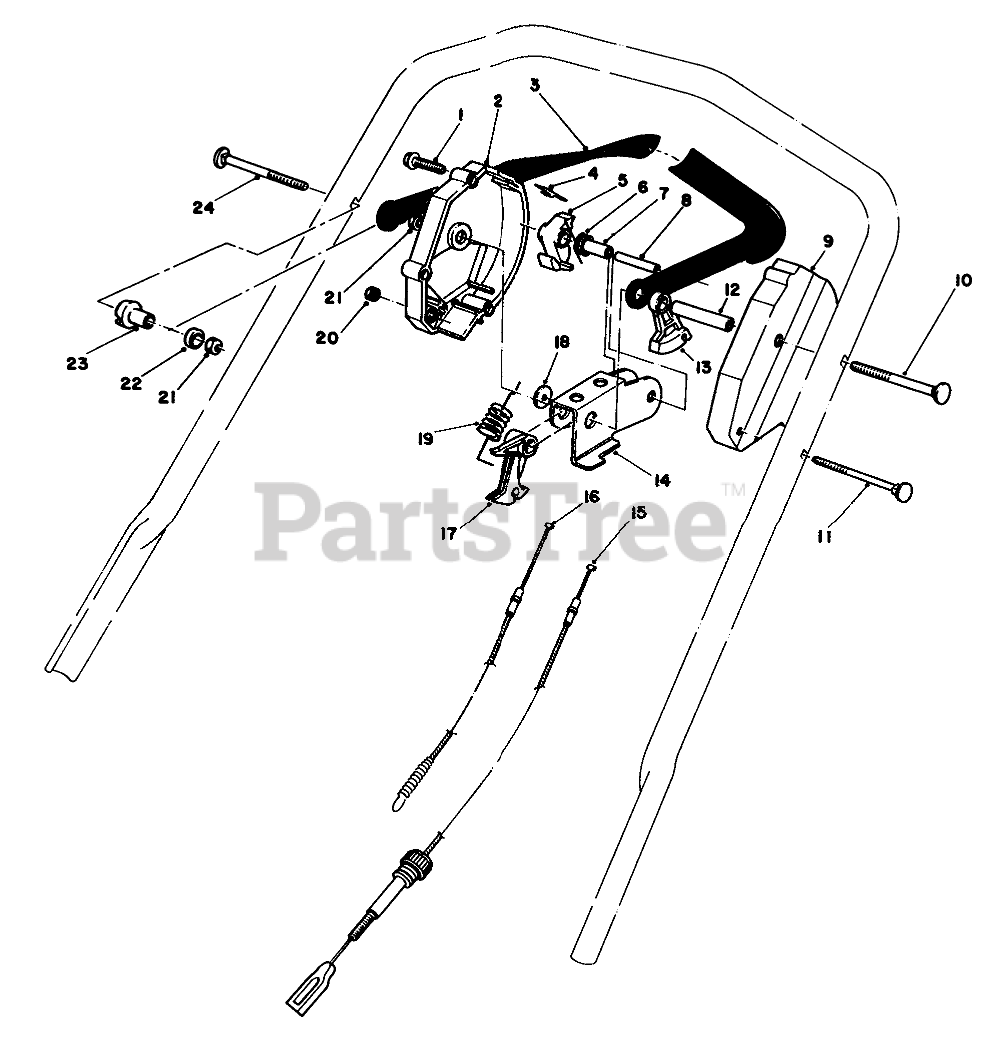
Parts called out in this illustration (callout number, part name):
1	SCREW-HWHTF
2	Housing Control R.H.
3	Bar-Control
4	LEAF SPRING
5	HOOK-CONTROL
6	SPRING-TORSION
7	SPACER
8	PIN-ROLL, SLOTTED
9	HOUSING-CONTROL, LH
10	5/16-18 X 3 HNDLE SCREW
11	HANDLE SCREW
12	TUBING-SPACER
13	LEVER-TRACTION
14	Rocker
15	TRACTION CABLE
16	Cable-Clutch
17	LEVER-CABLE
18	PLASTIC WASHER
19	Spring-Detent
20	NUT-LOCK, NI
21	NUT-LOCK, NI
22	SPACER-NYLON
23	SPACER-SUPPORT
24	5/16-18 X 2 HNDLE SCREW
